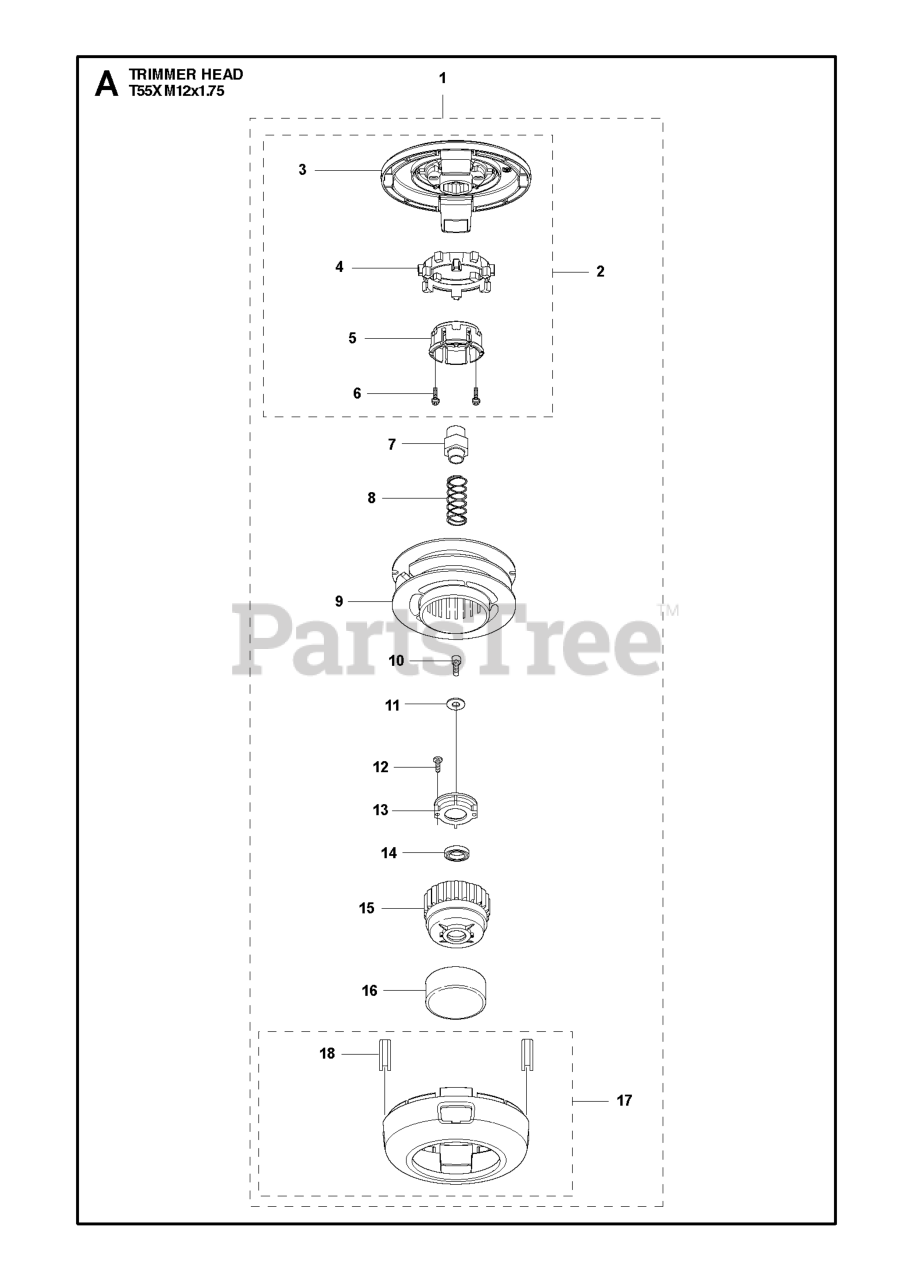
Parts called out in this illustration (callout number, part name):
2	HOUSING ASSY
5	RING FASTENER
14	BALL BEARING
